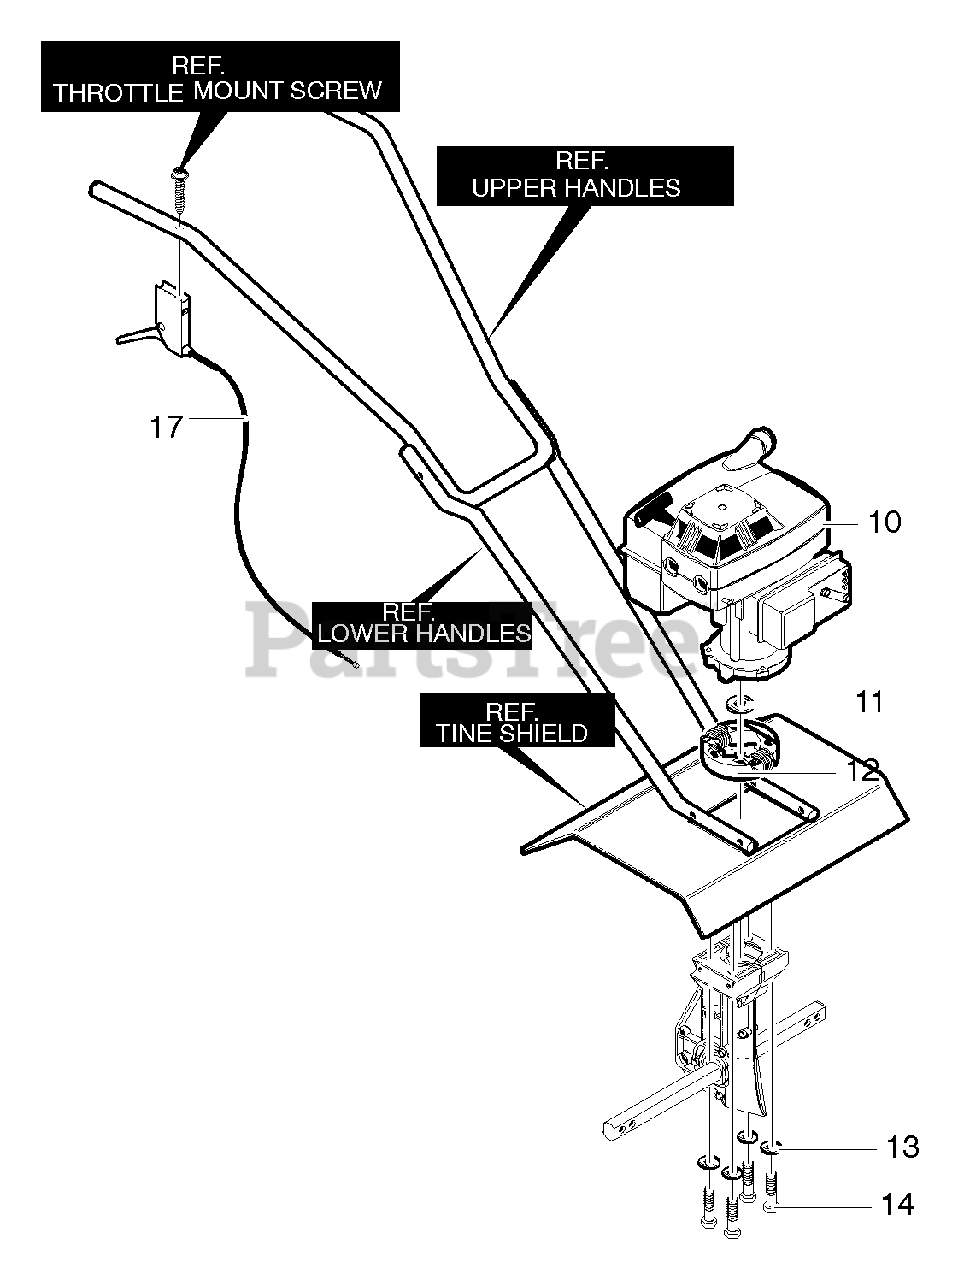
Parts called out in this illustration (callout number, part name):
10	Engine (2.0 HP)
11	Flat washer
17	Cable, Throttle
